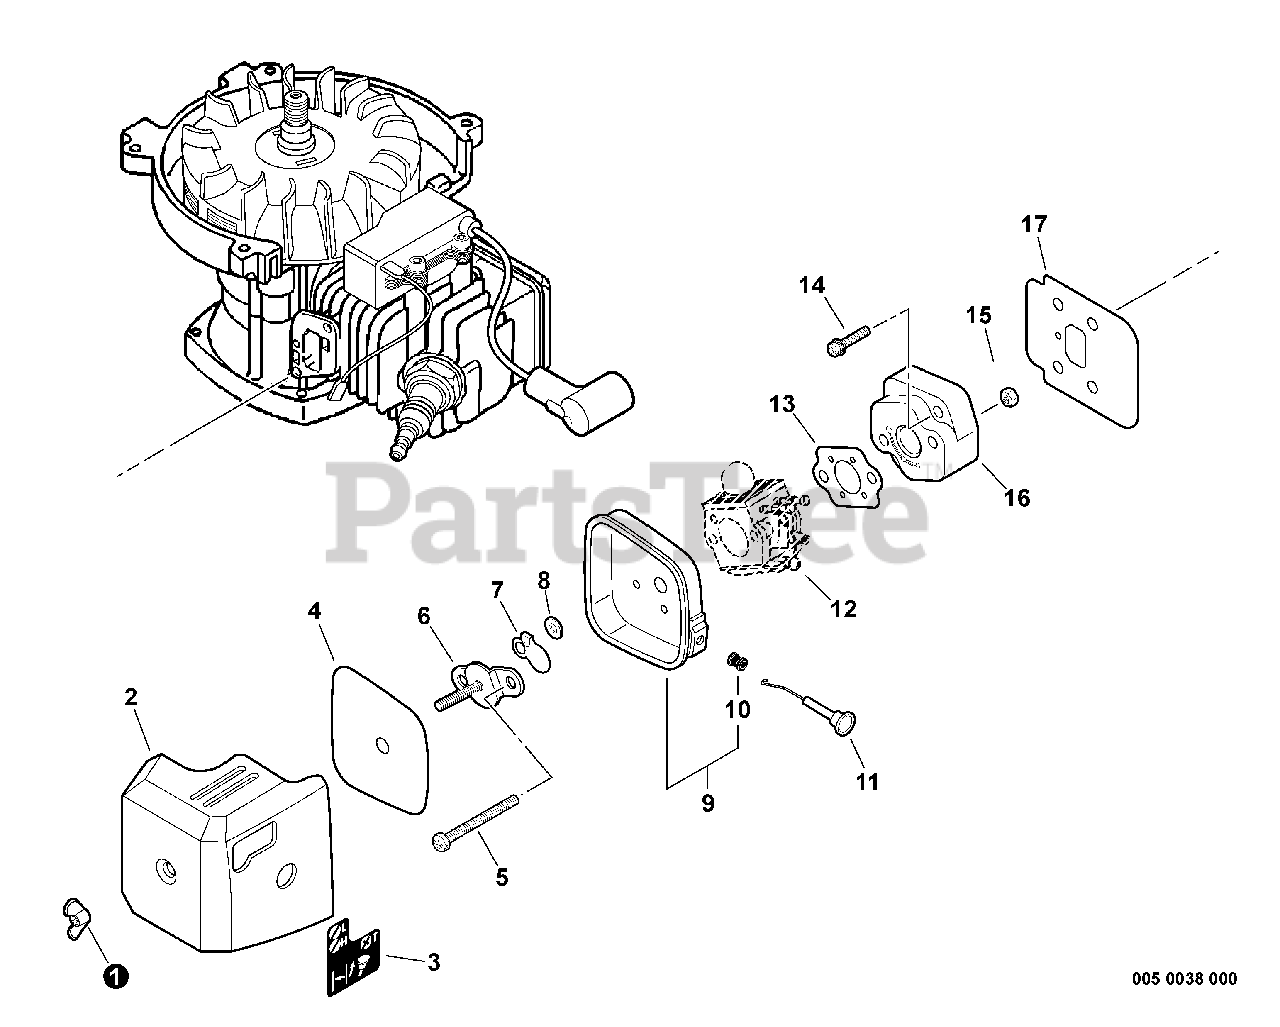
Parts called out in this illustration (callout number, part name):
1	WINGNUT - 6
2	COVER, AIR FILTER
3	LABEL - CHOKE
4	FILTER, AIR
5	SCREW - 5X57
6	PLATE, PREVENT
7	SHUTTER, CHOKE
8	WASHER - 5
9	CASE, AIR FILTER
11	ROD, CHOKE
12	CARBURETOR
13	GASKET, INTAKE
14	SCREW - 5X20
16	INSULATOR, INTAKE
17	SHIELD, INTAKE
